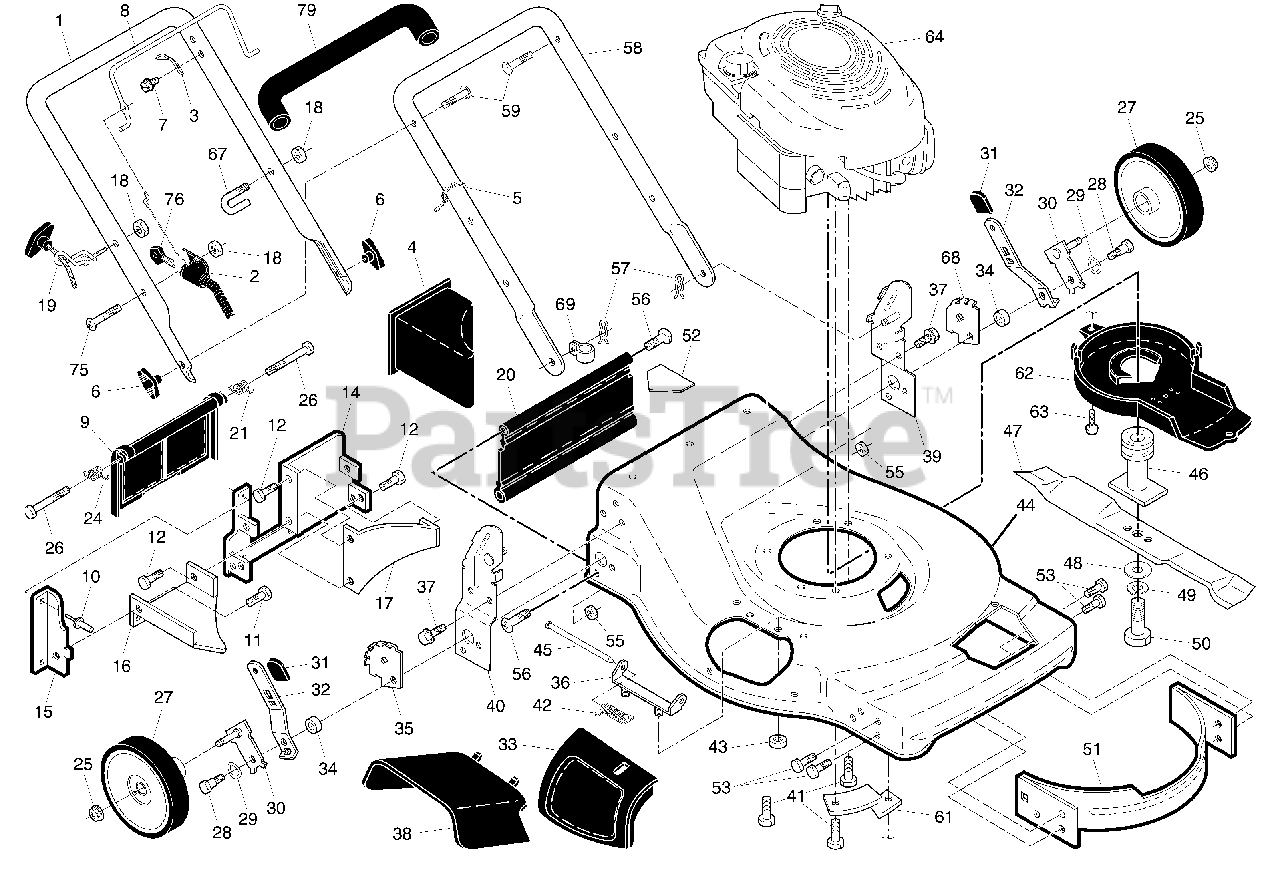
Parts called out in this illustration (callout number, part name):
1	Upper Handle
2	Key Start Switch
3	Bracket, Upstop
4	Mulcher Plug
5	Wire Tie
6	Handle Knob
8	Control Bar
9	Rear Door Assembly
11	Screw, Self-Tapping #10-24 x 5/8
12	Screw, Hex Hex Head, Sems 1/4-20 x 1/2
14	Back Plate
15	Side Baffle
16	Discharge Baffle
17	Rear Baffle
18	Keps Locknut 1/4-20
19	Rope Guide
20	Rear Skirt
21	Spring, Rear Door, LH
24	Spring, Rear Door, RH
25	Nut, Hex, Flanged
26	Bolt, Rear Door
27	Wheel & Tire Assembly, Rear
28	Bolt, Shoulder 3/8-16 x 1
29	Washer, Belleville
30	Axle Arm Assembly
31	Selector Knob
32	Selector Spring
33	Mulcher Door
35	Wheel Adjusting Bracket, RH
36	Hinge Bracket Assembly
37	Screw, Sems, Thread Cutting 5/16-18 x 3/4
38	Discharge Defl ector
39	Handle Bracket Assembly, LH
40	Handle Bracket Assembly, RH
41	Screw, Hex Head, Threaded, Rolled 3/8-16 x 1-1/8
42	Spring, Torsion
43	Nut, Hex, Nylock
44	Kit, Lawn Mower Housing
45	Rod, Hinge
46	Blade Adapter / Pulley
47	Blade, 22"
48	Washer, Hardened
49	Washer, Helical
50	Screw, Machine, Hex Head 3/8-24 x 1-3/8 Grade 8
51	Front Baffl e
52	Danger Decal
55	Nut, Hex
56	Screw, Hinge 1/4-20 x 1-1/4
57	Hairpin Cotter
58	Lower Handle
59	Handle Bolt
61	Bracket Debris Shield
62	Debris Shield
63	Screw, Debris Shield
67	Clip, Packaging
68	Wheel Adjusting Bracket, LH
69	Clip, Cable
